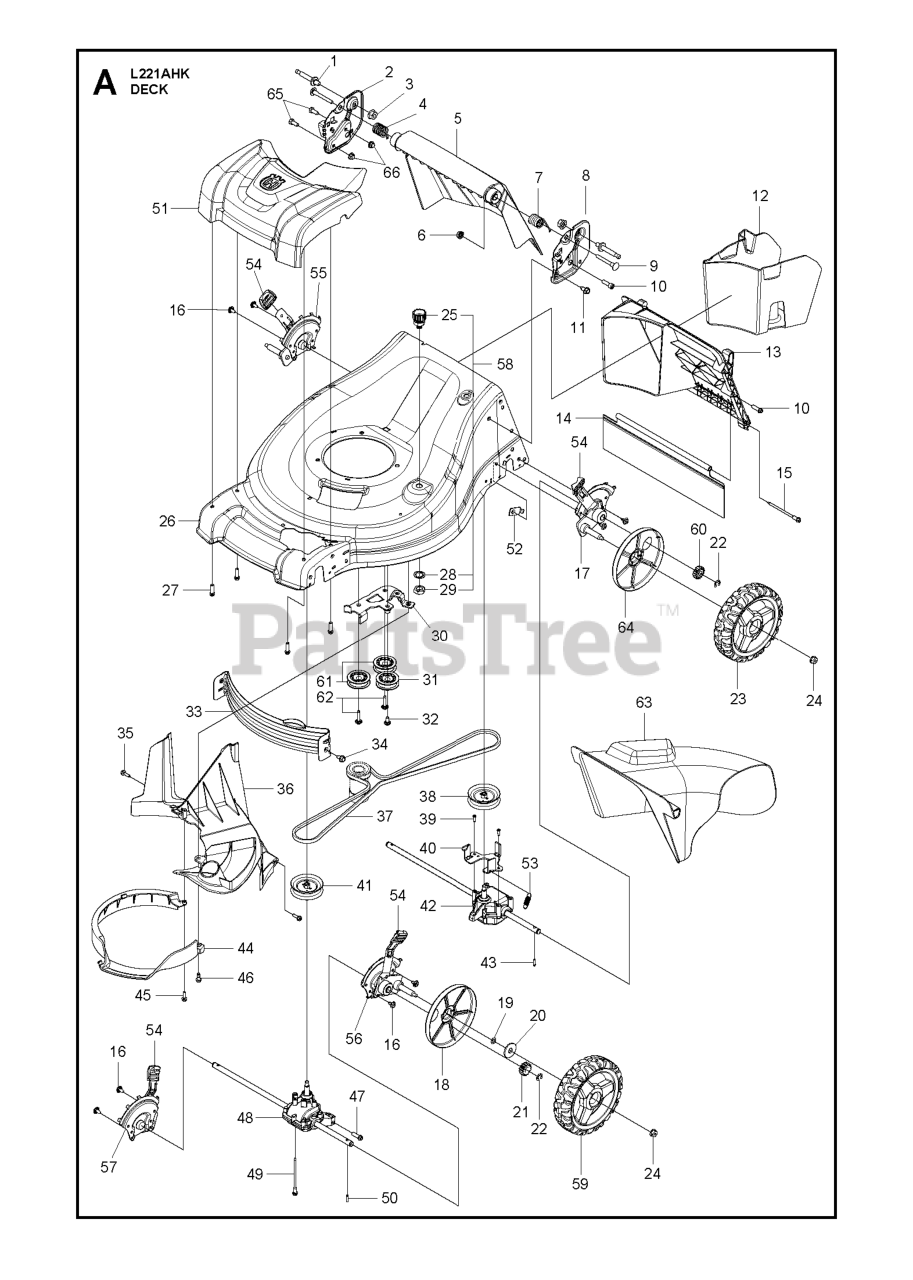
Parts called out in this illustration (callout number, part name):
1	BOLT.HAND.PIVOT.3125-18.21EFF
2	BRACKET.HANDLE.ADJ.21EF.RH.498
3	NUT.FLANGE.SERRAT.3125-18.5625
4	SPRING.RH.DOOR.21 EFF
5	DOOR REAR, 21IN EFF GRAY MS-49
6	NUT.FLANGED.3/8-16.ZINC
7	SPRING.LH.DOOR.21 EFF
8	BRACKET.HANDLE.ADJ.21EF.LH.498
9	BOLT.DOOR.PIVOT..375-16.21EFF
10	SCREW.HI-LO,5/16-14 X T-45
11	BOLT.5/16HEX.WHS.HD
12	PLUG.MULCH.21 EFF
13	INSERT.REAR.21 EFF
14	SKIRT.REAR.21 EFF
15	SCREW.HI-LO.5/16-14 X 4.10
16	SCREW
17	ADJUSTER.4PT.21EFF.LR.HW.BK
18	COVER.DUST.WHEEL.INNER.WALK
19	O-RING..070X.487.NEOPRENE
20	WASHER FLUT
21	PINIION.14.TOOTH.RGD
22	E-RING 7/16 RE
23	WHEEL.11.H3SP.AWD.LC.460.BB2
24	NUT.HEX.FLANGE.3/8-16.LO(3 2)
25	FITTING, HOSE, WATER WASHOUT
26	KIT.HSG.21EFF.AWD.WO.668.CE SY
27	SCREW.HI-LO. 5/16 X 1.00
28	WASHER.LOCK.INTERNAL.TOOTH
29	LOCKNUT.HEX.WITH.O-RING
30	BRACKET.ASM.IDLR.AWD.21EFF.BZP
31	PULLEY.RWD.IDLER.DBL SEAL
32	SCREW
33	BAFFLE.FRONT.21 EFF
34	BOLT.5/16HEX.WHS.HD
35	SCREW.HI-LO.13-16X.750.375XDRV
36	COVER.BELT/REAR BAFFLE.21 EFF
37	BELT.DRIVE.21EFF.AWD
38	PULLEY.DRIVE.SM.AWD/RWD
39	SCREW
40	BRACKET.TRAN.BELTKEEPER.22+RGD
41	PULLEY.DRIVE.SM.AWD/RWD
42	TRANSMISSION.AWD.REAR.21EFF
43	PAWL, DRIVE
44	RING.STRIPPER.21 EFF
45	SCREW.HI-LO.13-16X.750.375XDRV
46	BOLT SHOULDER_1/4-20_TRILOB
47	SCREW.HI-LO. 5/16 X 1.00
48	TRANSMISSION.AWD.FRONT.21EFF
49	SCREW.HI-LO.5/16-14 X 4.10
50	PAWL, DRIVE
51	COVER.DR.FULL.HUSQ.21EFF.AWD
52	STRAP.PLATE ATTACH.21 EFF.GLV
53	SPRING.RETURN.AUTO.
54	SELECTOR KNOB
55	ADJUSTER.4PT.21EFF.RR.HW.BK
56	ADJUSTER.4PT.21EFF.LF/RR.BLK
57	ADJUSTER.4PT.21EFF.RF/LR.BLK
58	KIT.WASH-OUT.PORT
59	WHEEL.8".AWD.3SP.EXT.DR.GREY
60	PINION.16.TEETH.HW.AWD.REAR
61	PULLEY.ASM.22+ AWD
63	CHUTE.DISCHARGE.21EFF.HW
64	COVER.DUST.WHEEL.HW.AWD.REAR
65	BOLT.FIN.HEX.5/16-18X3/4
66	NUTNYLOK.FLRANGE.5/16-18
